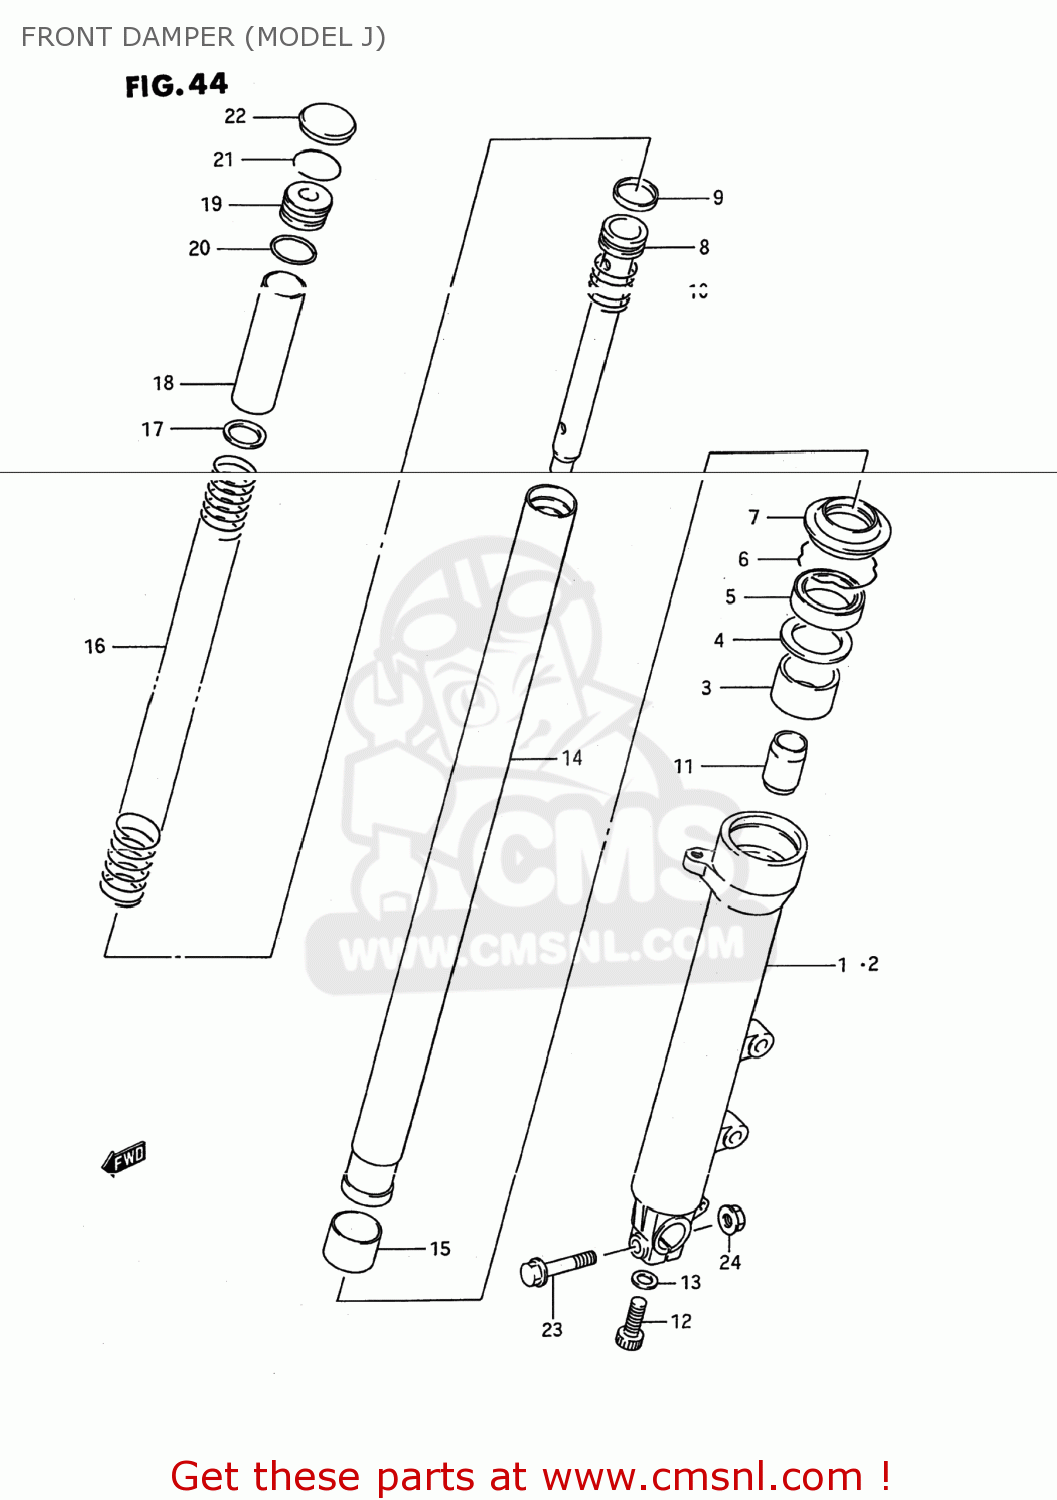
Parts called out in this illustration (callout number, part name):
1	TUBE,OUTER,RIGHT
2	TUBE,OUTER,LEFT
3	BUSH,GUIDE
4	SPACER,SEAL
5	OIL SEAL,FRONT FORK
6	CIRCLIP,FORK OIL SEAL
7	BOOT
8	CYLINDER
9	RING,PISTON
10	SPRING,REBOUND
11	PIECE,OIL LOCK
12	BOLT(8X27)
13	GASKET (NAS)
14	TUBE,INNER
15	BUSH,SLIDE
16	SPRING
17	JOINT,SPRING
18	COLLAR,SPRING
19	SEAT,SPRING
20	O RING
21	RING,STOPPER
22	CAP
23	BOLT, UPPER
24	NUT 8MM
